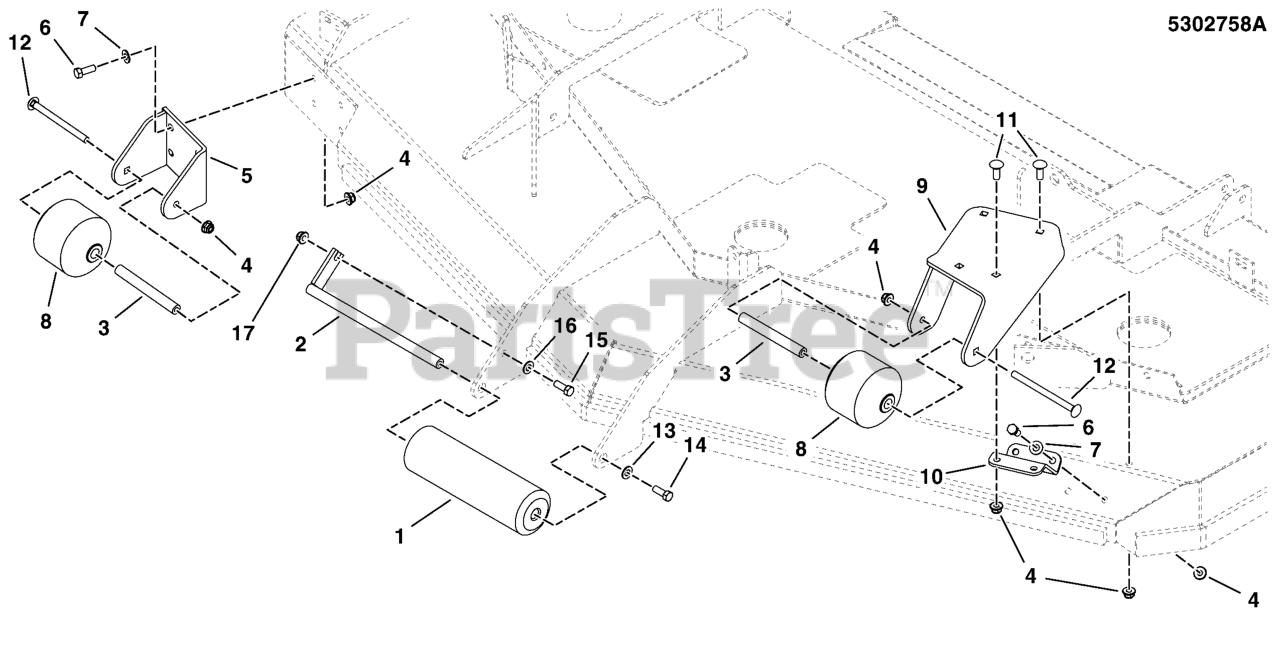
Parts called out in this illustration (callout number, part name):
1	ROLLER, DECK
3	SPACER, .38 X .63 X 4.31
4	NUT, 3/8-16 HEX NYLOCK FLANGE
5	PLATE, BRACKET, ANTI-SCALP - RED
6	BOLT, 3/8-16 X 1" GD5 CZ
7	WASHER, 3/8 SAE
8	ROLLER, SMALL
9	WELD, ANTI-SCALP BRACKET - RED
10	PLATE, ANTI-SCALP SUPPORT - RED
11	BOLT,3/8-16X1.00,RD SH SQ NK,GR 5,ZC/CL
12	BOLT, 3/8-16 X 5-1/2, CARRIAGE, GD5, CZ
13	WASHER, 5/16 USS
14	BOLT, 3/8-16 X 3/4" GD5 CZ
15	BOLT, 5/16-18 X 1 GD5 CZ
16	WASHER, 5/16 F436 FLAT
17	NUT, 5/16-18 HEX NYLOCK FLANGE
